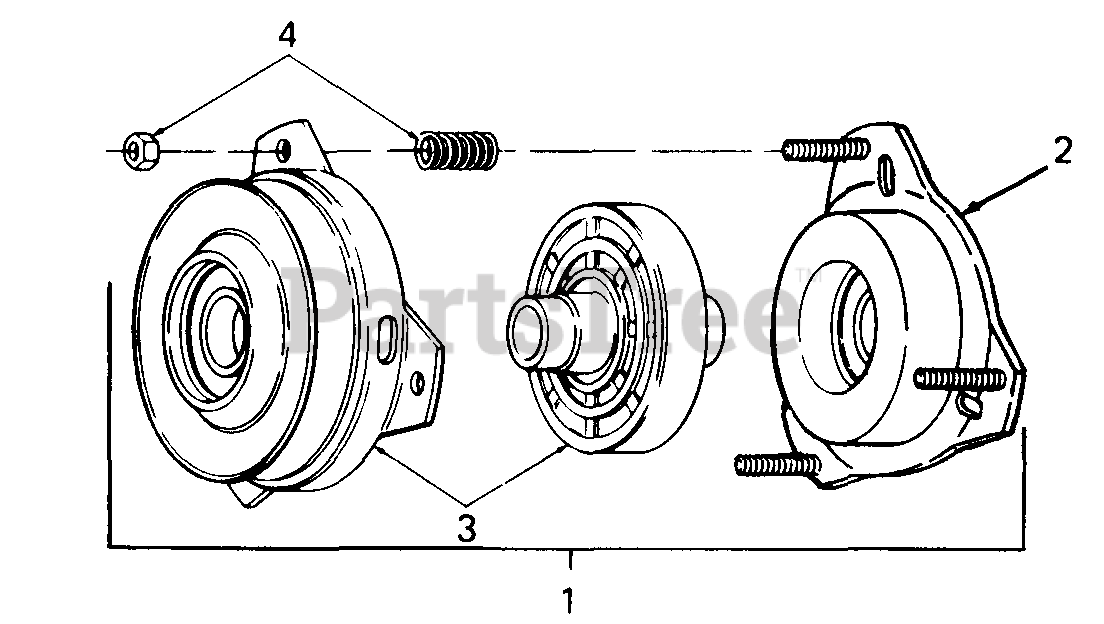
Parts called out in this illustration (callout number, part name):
1	Clutch Assy, PTO
2	Field Assy
3	Kit, Rotor & Armature
4	Mounting Accessories
